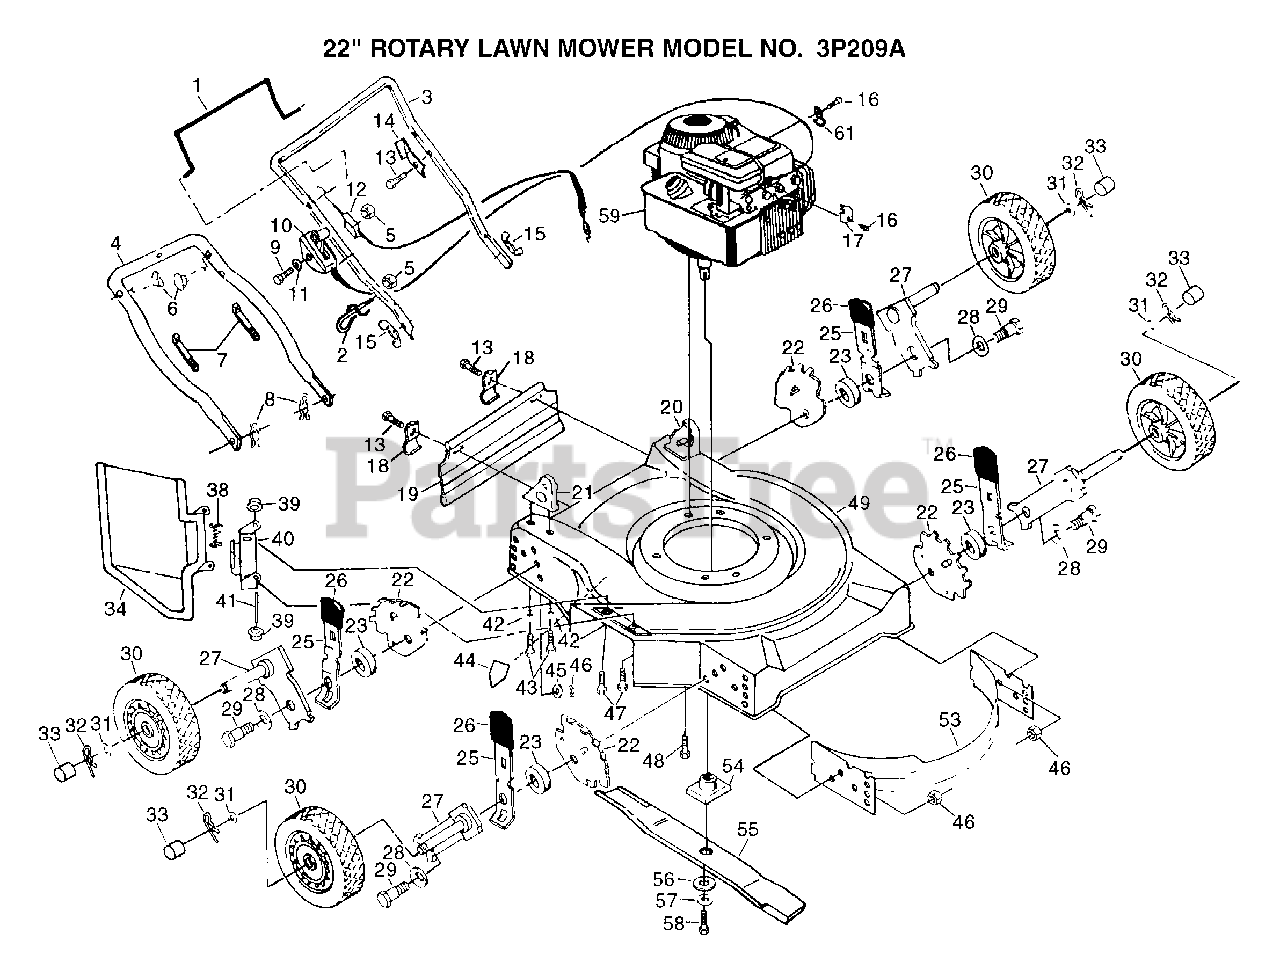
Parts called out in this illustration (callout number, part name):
1	CONTROL BAR PM
2	ROPE GUIDE
6	BOLT.HANDLE.LM
8	HAIRPIN COTTER
10	CONTROL THROTTLE
11	WASHER PM
12	"CABLE,ENG ZONE CO"
13	TAPPING SCREW
14	"BRKT,UPSTOP"
15	"NUT,WING PM"
16	SCREW PM
17	CABLE CLAMP
18	"BRKT,DEFL PM"
22	BRACKET.WHL.ADJ.9
25	SPRING SELECTOR
26	KNOB PM
27	AXLE ARM
28	"WASHER, BELLEVIL."
30	WHEEL.ASM
31	WASHER
32	RETAINER CLIP PM
33	HUB CAP-PLASTIC
38	"SPRING,TORSION"
39	PUSH ON SPEED NUT
40	"BRKT,HSG"
41	"ROD,HINGE "
42	STEEL WASHER
43	SCREW
44	DECAL HYT
46	LOCKNUT PM
47	SCREW
48	SCREW
49	KIT.HSG.22SD.PUSH
53	BAFFLE.FRT/REAR
54	BLADE ADAPTOR
55	"BLADE.22"""
56	"WASHER,HARDEN"
57	LOCKWASHER
58	SCREW
61	GUIDE CLIP PM
